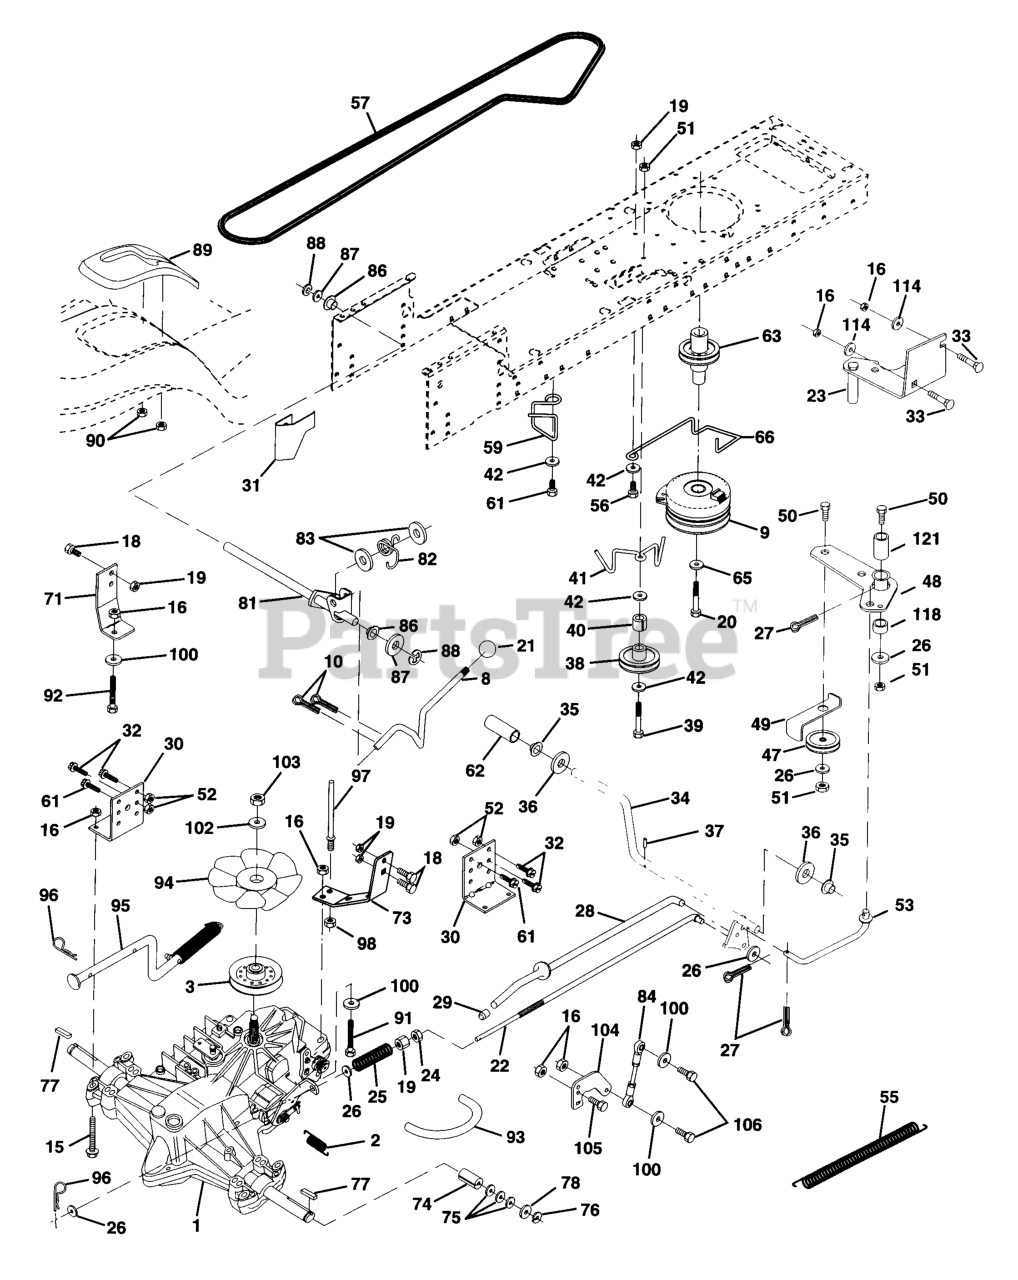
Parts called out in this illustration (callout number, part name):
1	TRANSAXLE ASSEMBLY
2	SPRING BRAKE
3	PULLEY, TRANSAXLE
8	ROD SHIFT FENDER
9	CLUTCH.ELECT.EVX.
10	PIN COTTER
15	BOLT HEX 5/16-18 GR 5
16	NUT.71038.31-18.HEX.NYLOCK
18	BOLT
19	NUT
20	BOLT HEX
21	KNOB.DELUXE.(PISTOL.GRIP).BLAC
22	ROD BRAKE HYDRO
23	BRACKET, ASM CLUTCH MTG
24	NUT
25	SPRING ROD LT
26	WASHER
27	COTTER PIN
28	ROD BRAKE PARK LT
29	PLUNGER CAP
30	BRACKET TRANSAXLE
31	KEEPER BELT LH
32	BOLT
33	RP BOLT 5/16-18 X3/4 ZN/YEL GR
34	SHAFT, FOOT PEDAL
35	BEARING.NYLON
36	WASHER LT
37	DRIVE PIN
38	PULLEY.IDLER.FLAT
41	KEEPER, BELT IDLER
42	WASHER
47	IDLER PULLEY
48	BELLCRANK ASSEMBLY
49	RETAIN BELT
50	BOLT
52	LOCKNUT
53	LINK, CLUTCH LT
55	SPRING, RETURN LT
57	DRIVE BELT, LTH & YTH TRACTORS
59	KEEPER CENTER SPAN
61	SCREW
62	COVER, PEDAL (1 2)
63	PULLEY, CLUTCH ELECT EVX
65	LOCKWASHER
66	KEEPER BELT ENGINE
71	STRAP LH TORQUE
73	STRAP TORQUE RH HYDRO
74	SPACER SPLIT
77	SQUARE KEY
81	SHAFT ASSY
82	SPRING,TORSION
83	WASHER
84	ROD.TIE.BALL.4.75
86	BUSHING.STEERING.ROD LTB-WSL
89	CONSOLE SHIFT
90	NUT.PUSH.3/16
91	BOLT.FIN HEX 5/16-18UNC X2 1/4
92	HEX BOLT
93	LINE FUEL HYD 4"
94	FAN 7" HYDRO
95	CONTROL ARM, BYPASS HYDRO
96	RETAINER M
97	KEEPER BELT RH
100	WASHER M
103	NUT.HEX.1/2-20
104	CONTROL ARM
106	BOLT.5/16-18X1-1/4 FULL.THREAD
114	Washer 11/32 x 3/4 x 14 Ga.
118	SPACER BELLCRANK
121	NYLINER CLUTCHING
